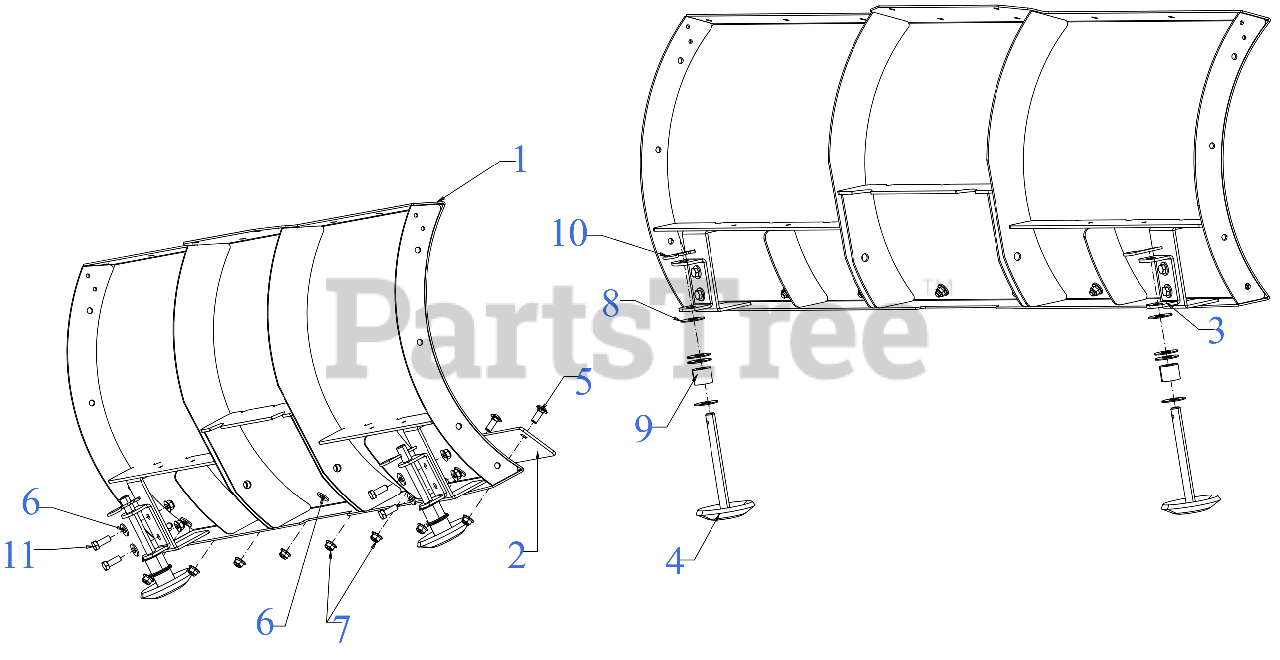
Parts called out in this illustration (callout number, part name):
1	72" PLOW BLADE
2	72" STEEL WEAR BAR
3	SKID FOOT BRACKET
4	SKID FOOT
5	SCREW 3/8-16X1.0 GR5
6	FLAT WASHER .385X.870X.090
8	FLAT WASHER-.63IDX1.595ODX.62
9	RUBBER BUSHING
10	5/8" COTTER PIN
11	SCREW 3/8-16 x 1 GR5
